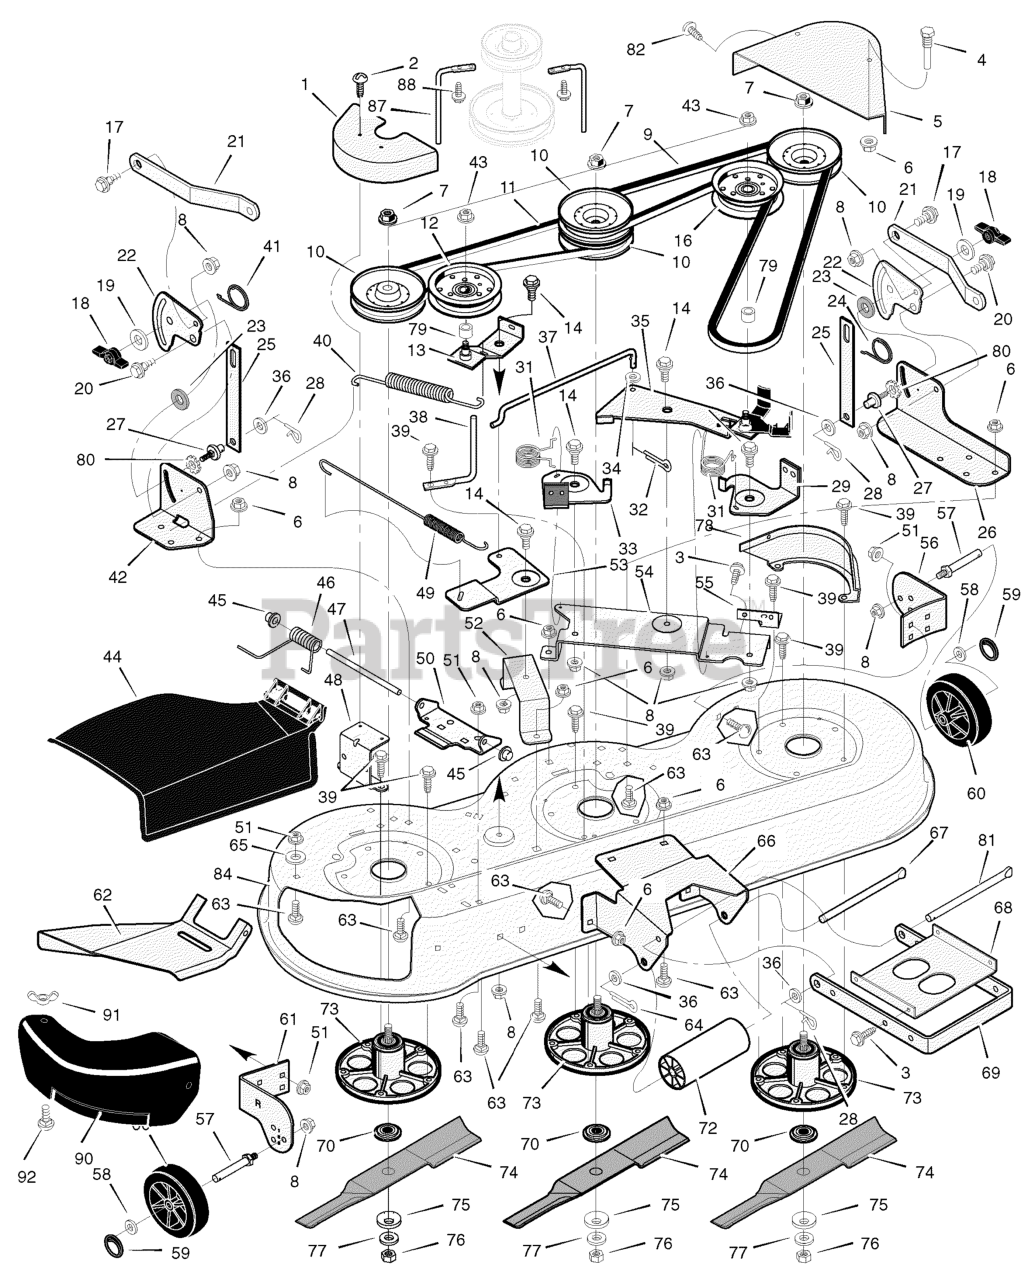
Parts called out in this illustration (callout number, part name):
1	Cover, Right Pulley
3	Screw
4	Guide, Belt
5	Cover, Left Pulley
6	Nut, Hex
7	Nut, Flange
8	Nut, Flange
9	Belt, Primary
10	Pulley
11	Belt, Secondary
12	Pulley, Idler
13	Arm, Idler
14	Bolt, Shoulder
16	Pulley, Idler
17	Bolt, Shoulder
19	Washer
20	Bolt, Shoulder
21	Bracket, Rear Suspension
22	Plate, Suspension
23	Pad, Friction
24	Spring
25	Link, Lift
26	Bracket, Left Lift
27	Pin, Hanger
28	Pin, Hair
29	Brake Assembly, Left
31	Spring
32	Pin, Cotter
33	Brake Assembly, Right
34	Washer
35	Idler, Arm
36	Washer
37	Link, Bell Crank
38	Guide, Belt
39	Screw
40	Spring, Extension
41	Spring, Torsion
42	Bracket, Suspension
43	Nut
44	Deflector, Chute
45	Push On Cap
46	Spring, Torsion
47	Rod, Deflector
48	Bracket, Cover
49	Spring, Extension
50	Bracket, Hinge
51	Nut, Flange
52	Bracket, Bell Crank
53	Crank, Bell
54	Plate, Brake Arm
55	Bracket, Brake Plate
56	Bracket, Left Gauge Wheel
58	Washer
59	Ring, Locking
60	Wheel, Gauge
61	Bracket, Right Gauge Wheel
62	Deflector, Inside
63	Bolt, Carriage
64	Pin, Cotter
65	Washer
66	Bracket, Front Deck
67	Rod, Hanger
68	Stiffener
69	Bracket, Suspension
70	Adapter, Blade
72	Roller
73	Housing, Jackshaft
75	Washer, Belleville
76	Nut
77	Washer
78	Bracket, Pulley Cover
79	Spacer
80	Washer
81	Rod, Hanger
82	Screw
84	Housing, Mower
87	Guide, Belt
90	Cover, Mulch
91	Wingnut
92	Bolt, Carriage
